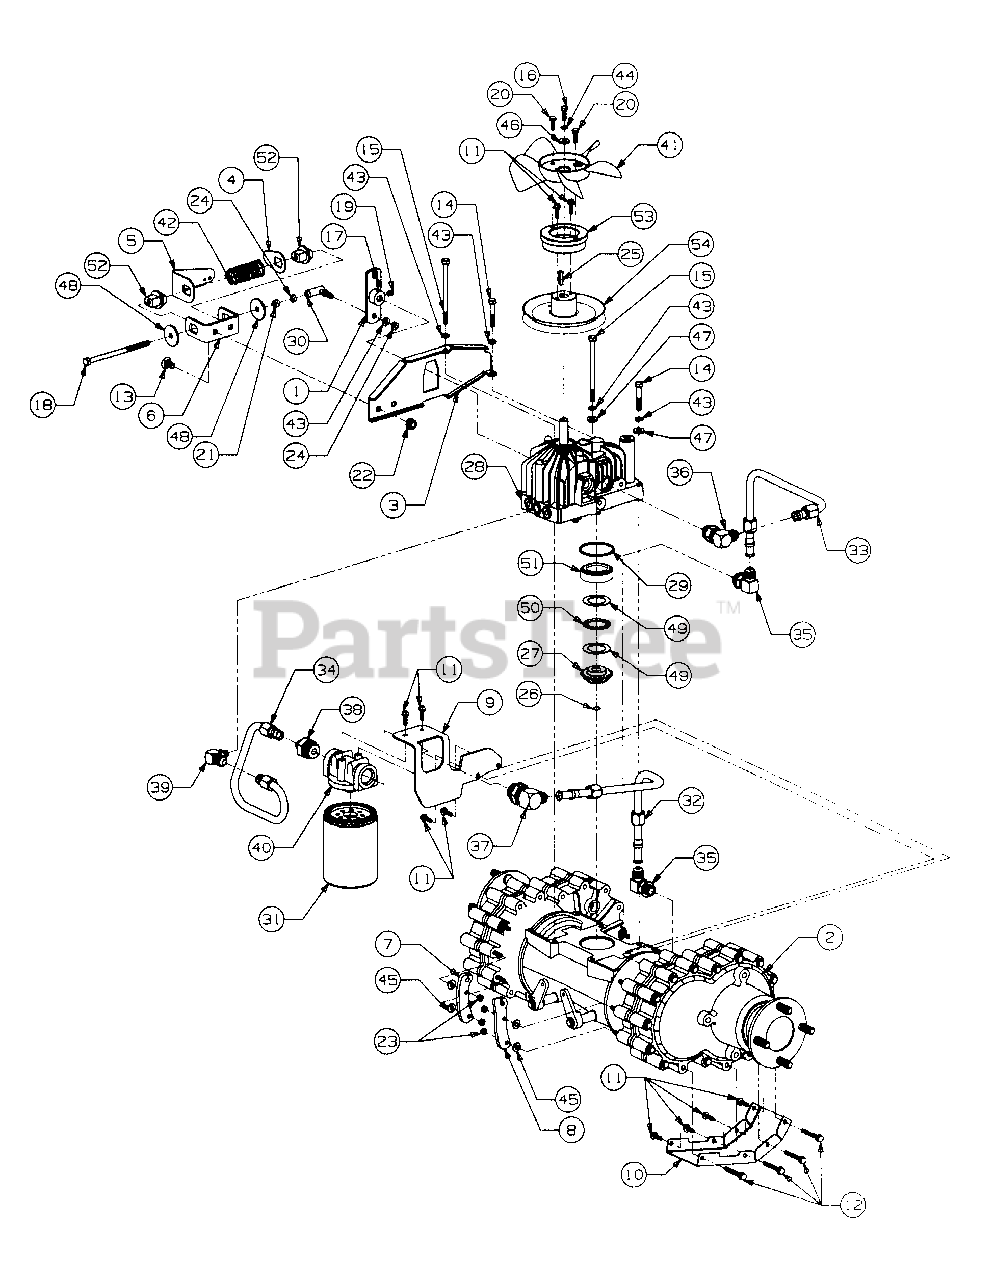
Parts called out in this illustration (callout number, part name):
1	Lever, Forward & Reverse
2	Transmission Assy, Complete
3	Plate, Neutral Mechanism Mtg
4	Stop, Switch
5	Mount, Switch
6	Bracket, Neutral Mechanism
7	Plate, Left Cable Mtg
8	Plate, Right Cable Mtg
9	Bracket, Oil Filter Mtg
10	Plate, Skid
11	Screw, Hex Wash Hd Tapp, 1/4-20 X .75 Lg
12	Screw, Hex Wash Hd Tapp, 1/4-20 X 2.31 Lg
13	Bolt, Sht Nk Carriage, 3/8-16 X .75 Lg GR5
14	Screw, Hex Cap, 5/16-18 X 1.75 Lg GR5
15	Screw, Hex Cap, 5/16-18 X 4.5 Lg GR5
16	Screw, Hex Cap, M6-1.0 X 20 mm Lg GR10.9
17	Set Screw w/Patch
18	Screw, Hex Cap, 5/16-24 X 5.37 Lg GR5
19	Set Screw w/Patch, 5/16-24 X .38 Lg
20	Screw, Hex Cap w/Patch, 1/4-20 X .75 Lg GR5
21	Nut, Hex, 5/16-24
22	Nut, Hex Flanged Lock, 3/8-16
23	Nut, Hex Top Lock, 1/4-20
24	Nut, Hex Jam 5/16-24 GR5
25	Key, Square, 5 mm X 5 mm X 25 mm Lg
26	Ring, Snap, .500 Dia Shaft
27	Gear, Input Pinion - 20T
28	Pump, Hydrostatic
29	O-Ring, 2.237 ID X .103 Thk
30	Ball Joint
31	Filter, Oil
32	Tube, Filter Inlet
33	Tube, Return
34	Tube, Hydro Inlet
35	Elbow, 90 Deg w/O-Ring
36	Elbow, 90 Deg w/O-Ring
37	Elbow, 90 Deg w/O-Ring
38	Connector, Straight w/O-Ring
39	Elbow, 90 Deg w/O-Ring
40	Head, Filter
41	Fan, Hydro 8"
42	Spring, Compression, 1.20 OD X 2.70 Lg
43	Washer, Lock, 5/16
44	Washer, Lock, 1/4
45	Washer, Flat, .25 X .62 X .0515 Thk
46	Washer, Flat, .25 X .750 X .119 Thk
47	Washer, Flat, .312 X .750 X .119 Thk
48	Washer, Flat, .206 X .448 X .105 Thk
49	Washer, Thrust, 1.25 X 1.937 X .031 Thk
50	Bearing, Thrust, 1.25 X 1.937 X .0781 Thk
51	Spacer, Input Pinion
52	Guide Neutral Stop
53	Hub, Fan Mtg
54	Pulley, Transmission Drive
